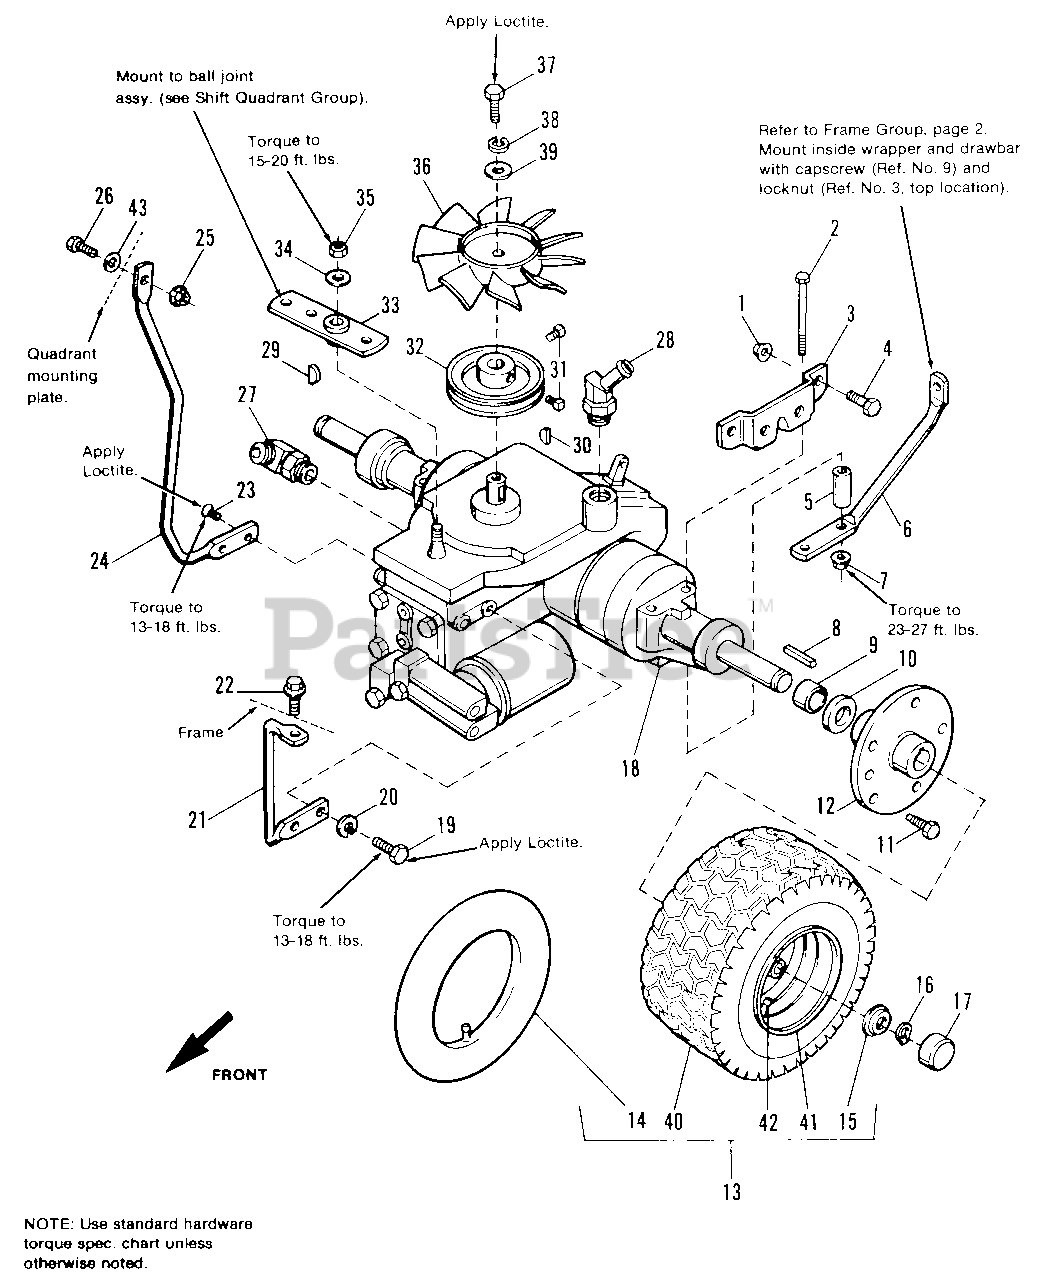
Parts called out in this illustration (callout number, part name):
1	NUT, Hex Flange, Whiz Lock, 3/8-16
2	CAPSCREW, 3/8-16 x 4
3	BRACKET, Transaxle Mounting
4	CAPSCREW, 3/8-16 x 1
5	SPACER, 1-1/4
6	BRACE, Transaxle, Rear, L.H.
6	BRACE, Transaxle, Rear, R.H.
7	NUT, Hex, Two-Way Lock, 3/8-16
8	KEY, Straight
9	SPACER, Wheel
11	BOLT, Wheel
12	HUB ASSY., Rear Wheel (Standard)
12	HUB ASSY., Right Rear Wheel 4" Offset used with Electric Lift Kit
13	TIRE & WHEEL ASSY., 23 x 10.50 x 12
15	RETAINER, Hub Cap
16	RING, Retainer
18	TRANSAXLE (See pages 16-21 for breakdown)
19	CAPSCREW, 5/16-18 x 3/4
20	LOCKWASHER
21	TORQUE ARM
22	SCREW, Taptite, 5/16-18 x 5/8
23	SCREW, 5/16-18 x 3/4
24	BRACE, Transaxle, RH
25	NUT, Whiz Flange, 5/16-18
26	CAPSCREW, 5/16-18 x 1
27	FITTING, Hydro
28	FITTING, Hydro
29	KEY, Woodruff (#3)
30	KEY, Hi-Pro
31	SET SCREW, 1/4-28 x 1/2
33	CONTROL ARM ASSY. (Speed)
34	WASHER
35	NUT, Hex, Center-Lock, 3/8-16
36	FAN, 10-Blade (C.C.W.)
37	CAPSCREW, 1/4-20 x 3/4
38	LOCKWASHER
39	WASHER
40	TIRE, 23 x 10.50-12
42	VALVE STEM
